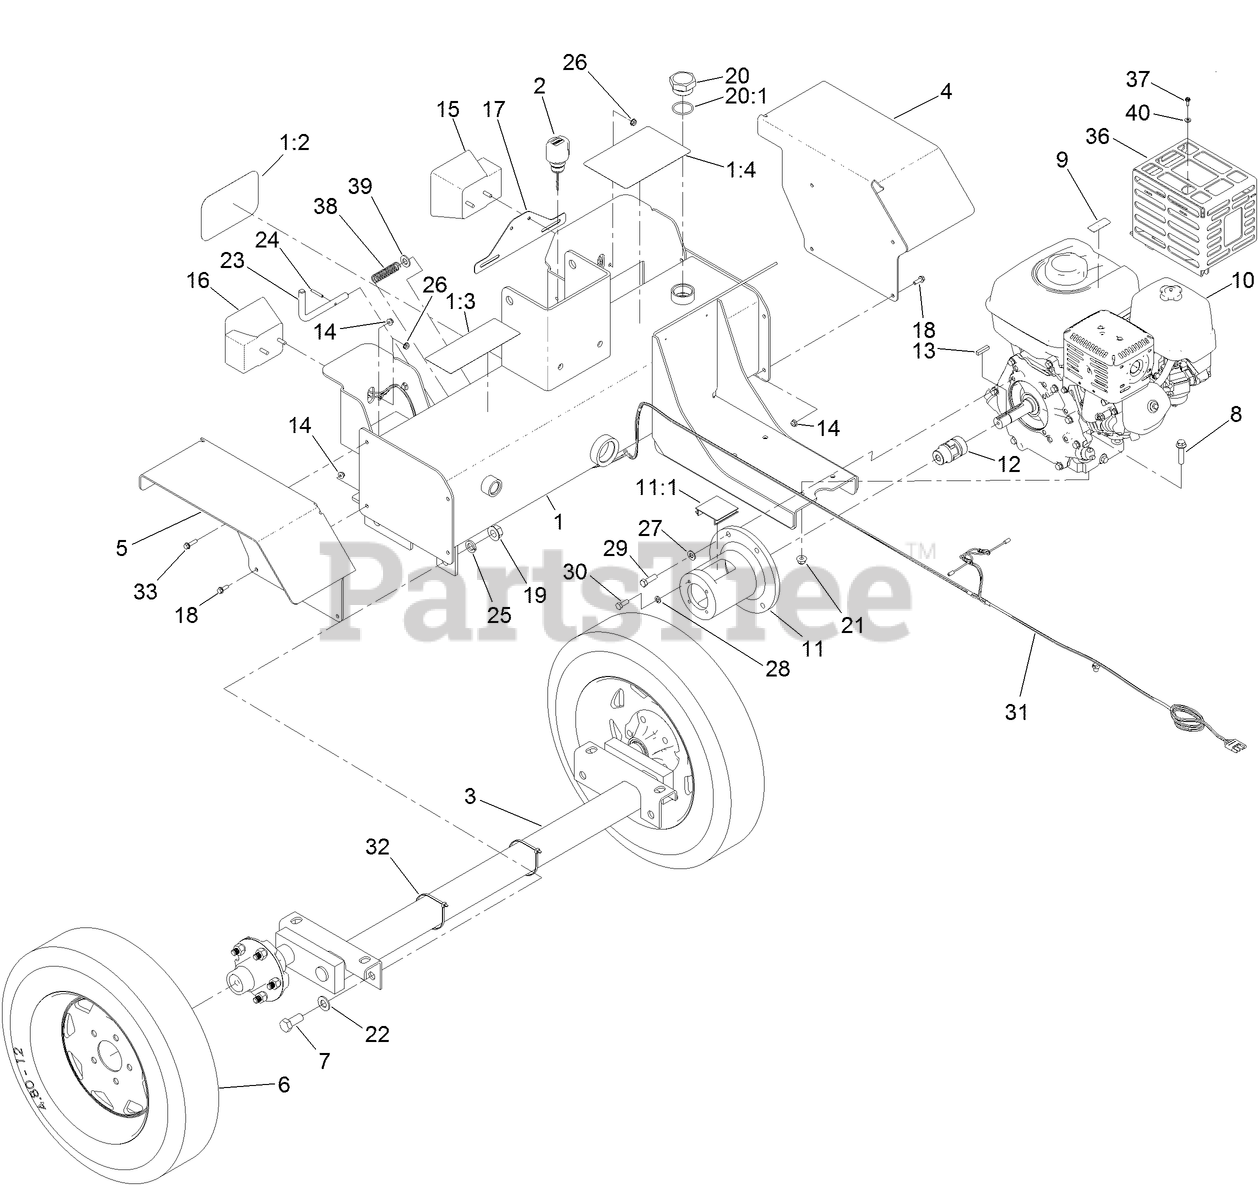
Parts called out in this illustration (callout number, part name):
1	HYD TANK ASM
1:2	DECAL
1:3	DECAL-WARNING
1:4	DECAL-SERVICE
2	BREATHER
3	AXLE ASM
4	FENDER-LH
5	FENDER-RH
6	WHEEL AND TIRE ASM
7	SCREW-HH
8	SCREW-HHF
9	DECAL-WARNING, ETHANOL
10	ENGINE-HONDA, GX270
11	HOUSING-MOUNT,PUMP
11:1	COVER-ACCESS
12	COUPLER-FLEX
13	KEY-SQUARE
14	NUT-HF
15	LIGHT-TAIL, LH
16	LIGHT-TAIL, RH
17	HOLDER-PLATE, LICENSE
18	SCREW-HHF
19	NUT-FLANGE
20	PLUG-HH
20:1	O-RING
21	NUT-HF, NI
22	WASHER
23	PIN-LATCH
24	PIN-ROLL
25	WASHER-LOCK
26	NUT-KEPS
27	WASHER-FLAT
28	SCREW-HH
29	SCREW-HH
30	SCREW-HH
31	HARNESS-WIRE
32	TIE-CABLE
33	SCREW-HHF
36	GUARD-MUFFLER
37	SCREW-HSBH
38	SPRING-COMPRESSION
39	WASHER-FLAT
40	WASHER-FLAT
